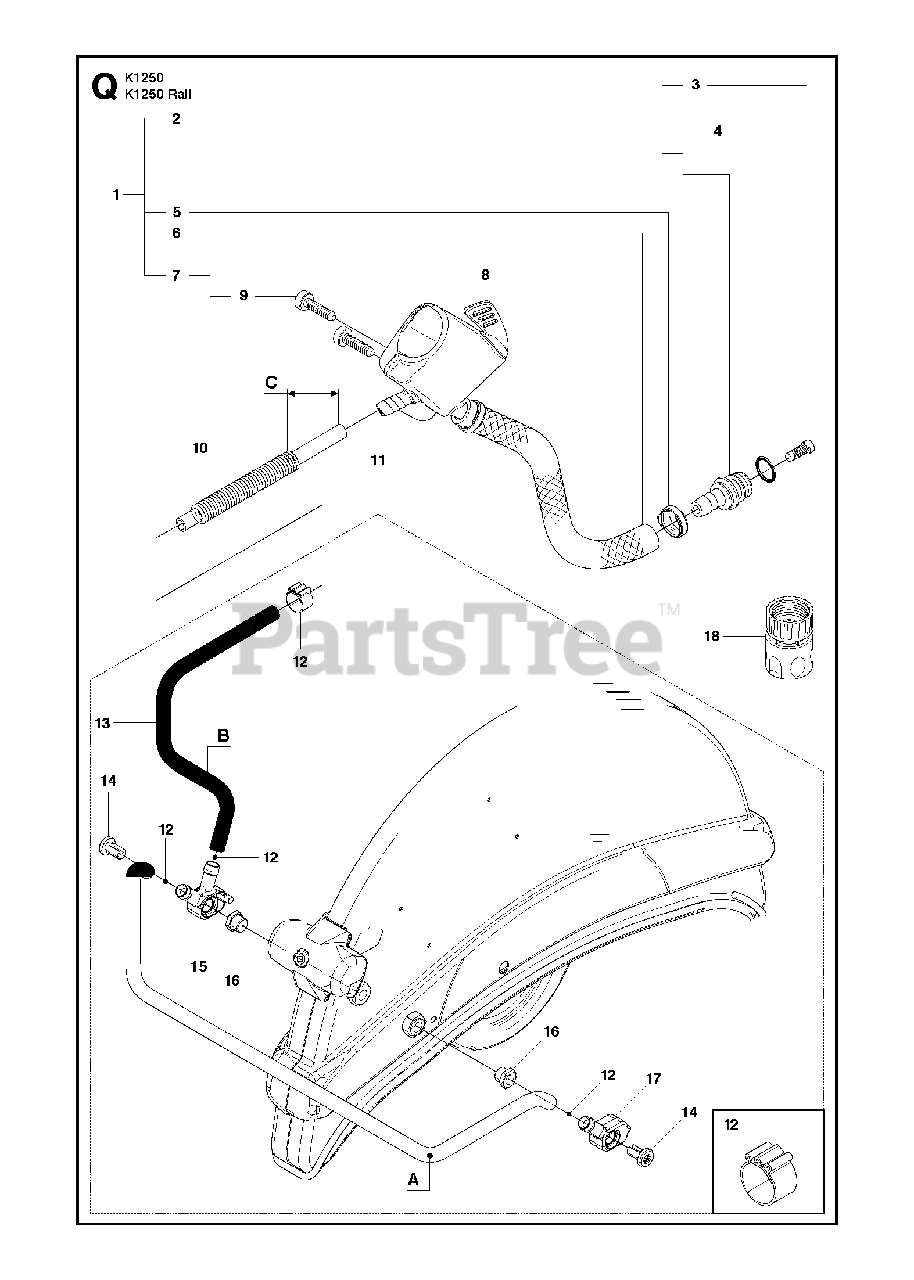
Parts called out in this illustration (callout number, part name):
1	HOSE KITIncl, 2, 5-7
2	NIPPLEIncl. 3, 4
5	HOSE CLAMP
6	HOSEL=230 mm
7	VALVE ASSYIncl. 8
10	PROTECTIVE SPRING
13	HOSEL=270mm
14	SCREW ITXSCM
18	COUPLERUSA, Canada
